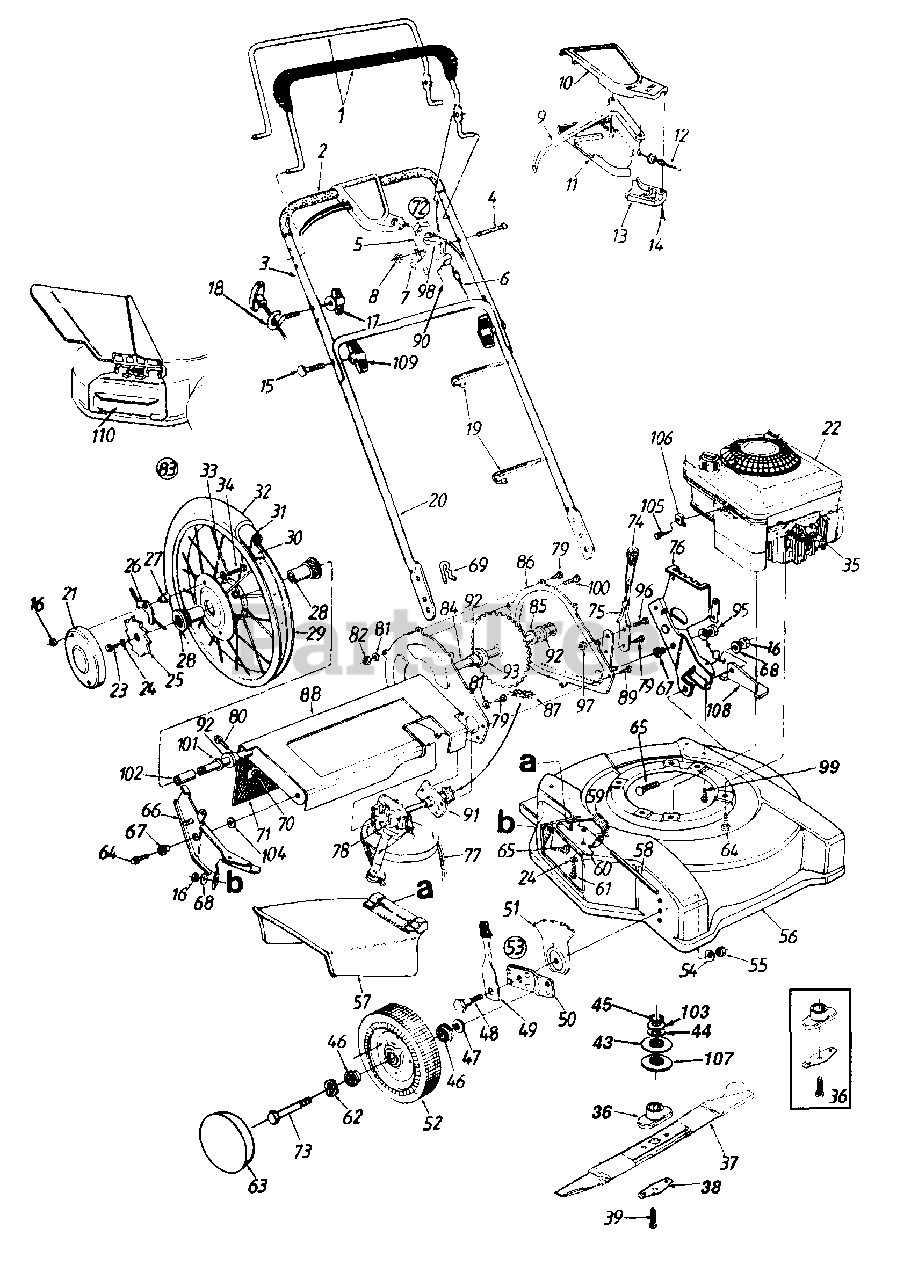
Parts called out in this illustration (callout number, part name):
1	Control Handle Ass'y.
2	Foam Grip
4	Oval C-Sunk Scr.
5	Throttle Body
6	Control Cable 39" Lg.
7	Spring Wash. .66" I.D.
8	Hex L-Nut 1/4-20 Thd.
9	Control Lever
10	Control Cover Half Upper
11	Control Cover Half Lower
12	Self-Propelled Cable 48" Lg.
13	Cable Mounting Cap
14	Fl-"C" Sunk Hd. Tap Scr. #10 x .75" Lg.
15	Curved Hd. Bolt 5/16-18 x 2" Lg.
16	Hex Nut 5/16-18 Thd.
17	Handle Knob 1/4-20 Thd.
18	Rope Guide
19	Cable Tie
22	Engine
23	Hex Bolt 1/4-20 x .75" Lg. (Gr. 5)
24	Bell-Wash. 1/4" I.D.
25	Wheel Ratchet
26	Pawl and Spring Ass'y.
27	Special Hex Nut 5/16-18 Thd.
28	Flange Bearing .63" I.D.
29	Rim Ass'y. Only 16" x 2.1"
30	Rimstrip 16" x 7/8"
31	Inner Tube 16" x 2.12"
32	Chevron Tire 16" x 2.125"
33	Intern. L-Wash. 5/16" I.D.
34	Hex Bolt 5/16-18 x 1.0" (Gr. 5)
35	Spark Plug Boot
36	Blade Adapter Kit
37	22" Mulching Blade
38	Blade Bell Support
39	Hex Bolt 3/8-24 x 1.5" Lg.
43	Upper Pulley Half
44	Fl-Wash. .88" I.D.
45	Crankshaft Spacer
46	Ball Bearing 1/2" I.D.
47	Bell-Wash. .38" I.D.
48	Shld. Bolt .5"
49	Spring Lever Ass'y. w/Knob
51	Height Adj. Plate
52	Wheel Ass'y. Comp.
53	Height Adj. Ass'y. Comp. R.H.
54	Bell-Wash. .39" I.D. x 1.38"
55	Hex Nut 3/8-16 Thd.
58	Hinge Pin
59	Torsion Spring
60	Adapter Plate
61	Hex TT-Tap Scr. 1/4-20 x .5"
62	Wave Wash. .51" I.D. x .78"
63	Hub Cap
64	Hex TT-Tap Scr. 3/8-16 x 1"
65	Carriage Bolt 5/16-18 x .62" Lg.
68	Bell-Wash. 5/16" I.D.
69	Intern. Cotter Pin 5/16" Dia.
70	Retaining Strip
71	Rear Flap
72	Throttle Box Comp.
73	Front Axle Bolt
75	Height Adjustment Lever
78	Transmission Comp.
79	Hex Tap Scr. 1/4 x .38" Lg.
80	Hex Tap Scr. 1/4 x .62" Lg.
81	L-Wash. 1/4" I.D.
82	Hex Nut 1/4-20 Thd.
83	Wheel Ass'y. Comp.
84	Sprocket and Axle Ass'y.
85	Fl-Wash. .635" I.D. x 1.0" O.D.
90	Throttle Cable
92	Hex Flange Brg. .631" I.D.
93	Spacer .63" I.D. x 1.25"
95	Hex L-Nut 3/8-24 Thd.
96	Hex Bolt 3/8-16 x .625" Lg.
97	Flanged L-Nut 3/8-16 Thd.
98	Throttle Lever
99	Hex B-Tap Scr. 5/16-18 x .5"
100	Hex Bolt 1/4-20 x .5" Lg.
101	Fl-Wash. .632" I.D. x .943"
102	Spacer .635" I.D. x .88" x .790
103	Spr. Wash. .89" I.D.
104	Fl-Wash. .38" I.D. x 1" O.D.
105	Wash. Hd. Scr. #10-32 x .62" Lg.
106	Casing Clamp
107	Lower Pulley Half
108	Deck Bracket
109	Hand Knob
